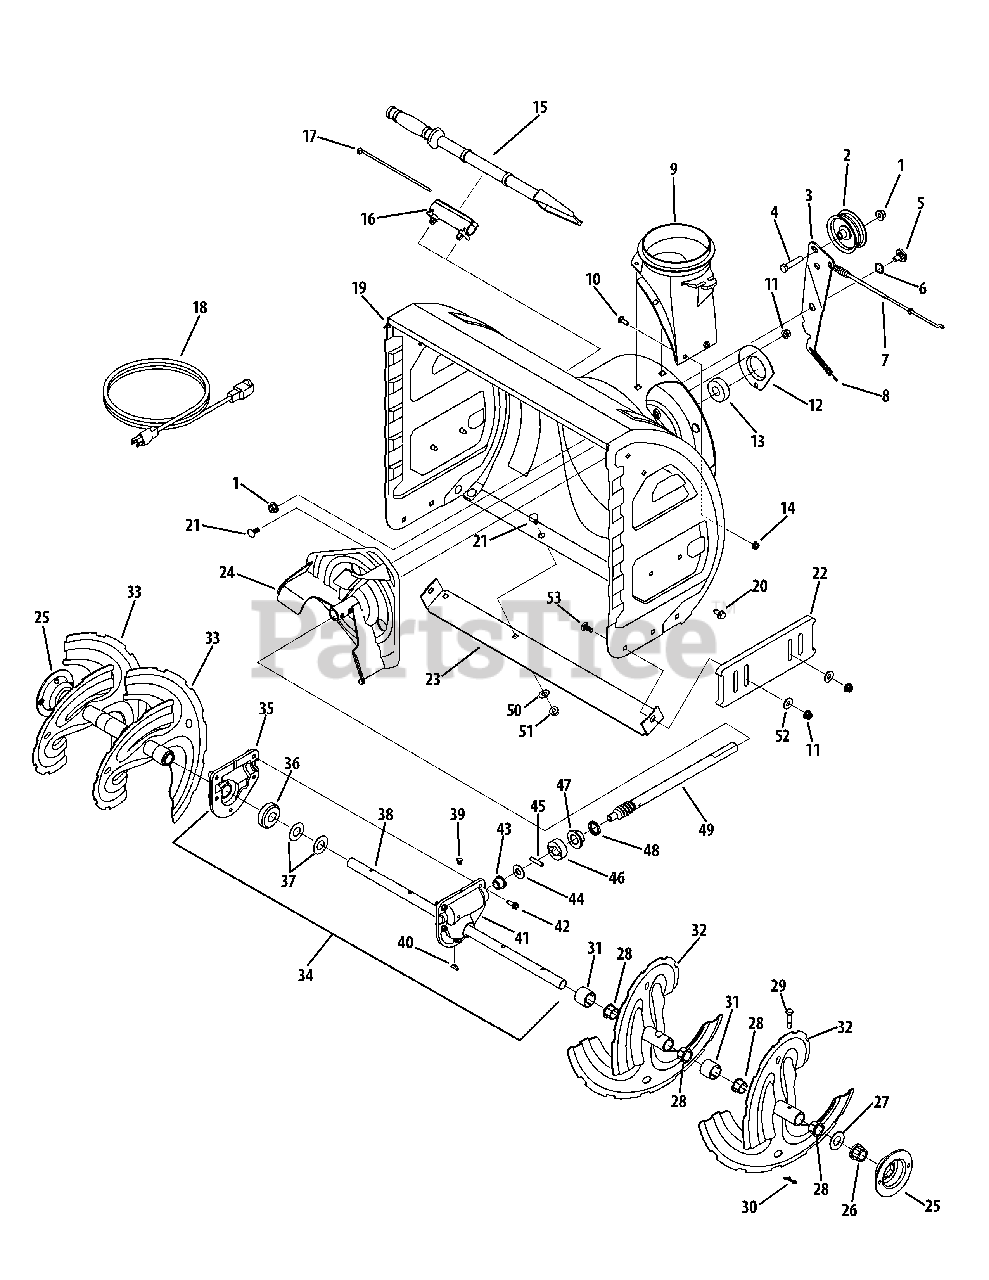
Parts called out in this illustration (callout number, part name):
1	Flange Lock Nut, 3/8-16
2	Idler Pulley
3	Auger Idler Bracket w/ Brake
4	Hex Bolt, 3/8-16 x 1.75
5	Shoulder Screw, .625 x .17 x 3/8-16
6	Wave Washer, .625 x .885 x .015
7	Clutch Cable
8	Extension Spring, .38 OD x 3.6
9	Chute Adapter, 5.0
10	Carriage Screw, 1/4-20 x .75
11	Flange Lock Nut, 5/16-18
12	Bearing Housing
13	Ball Bearing, .75 ID x 1.85 OD
14	Flange Lock Nut, 1/4-20
15	Cleanout Tool
16	Cleanout Tool Mount
17	Cable Tie, 3/16 x .05 x 7.4
18	Extension Cord, 3-Prong
19	Auger Housing, 26"
20	Hex Washer Screw, 5/16-18 x .750
21	Carriage Bolt, 5/16-18 x .750
22	Deluxe Polymer Skid Shoe
23	Stainless Steel Shave Plate, 26"
24	Impeler Assembly
25	Bearing Housing
26	Hex Flange Bearing
27	Flat Washer, .76 x 1.49 x .06
28	Flange Bushing .800 ID x .910 OD
30	Bow-Tie Cotter Pin
31	Spacer, 1.25 OD x .75 ID x 1.00
32	Spiral Assembly, LH
33	Spiral Assembly, RH
34	Gearbox Assembly, 26"
35	Housing Assembly, RH
36	Worm Gear, 2OT
37	Flat Washer, .760 ID x 1.50 OD
38	Auger Axle, 26"
39	Plug, 1/4 x .437
40	Hi-Pro Key, 3/16 x 5/8
41	Housing Assembly, LH
42	Hex Washer Screw, 1/4-20 x .750
43	Flng. Bearing, .50 ID x .75 OD x .59
44	Flat Washer, .51 x 1.12 x .06
45	Dowel Pin, .25 OD x 1.25
46	Thrust Collar, .756 ID x .600
47	Flng. Bearing, .75 ID x 1.0 OD x.59
48	Oil Seal, .75 x 1.131 x .188
49	Worm Shaft, .75 OD
50	Bell Washer, .340 x .872 x .060
51	Hex Nut, 5/16-18
52	Flat Washer, .349 x .879 x .063
53	Carriage Screw, 5/16-18 x 1.00
